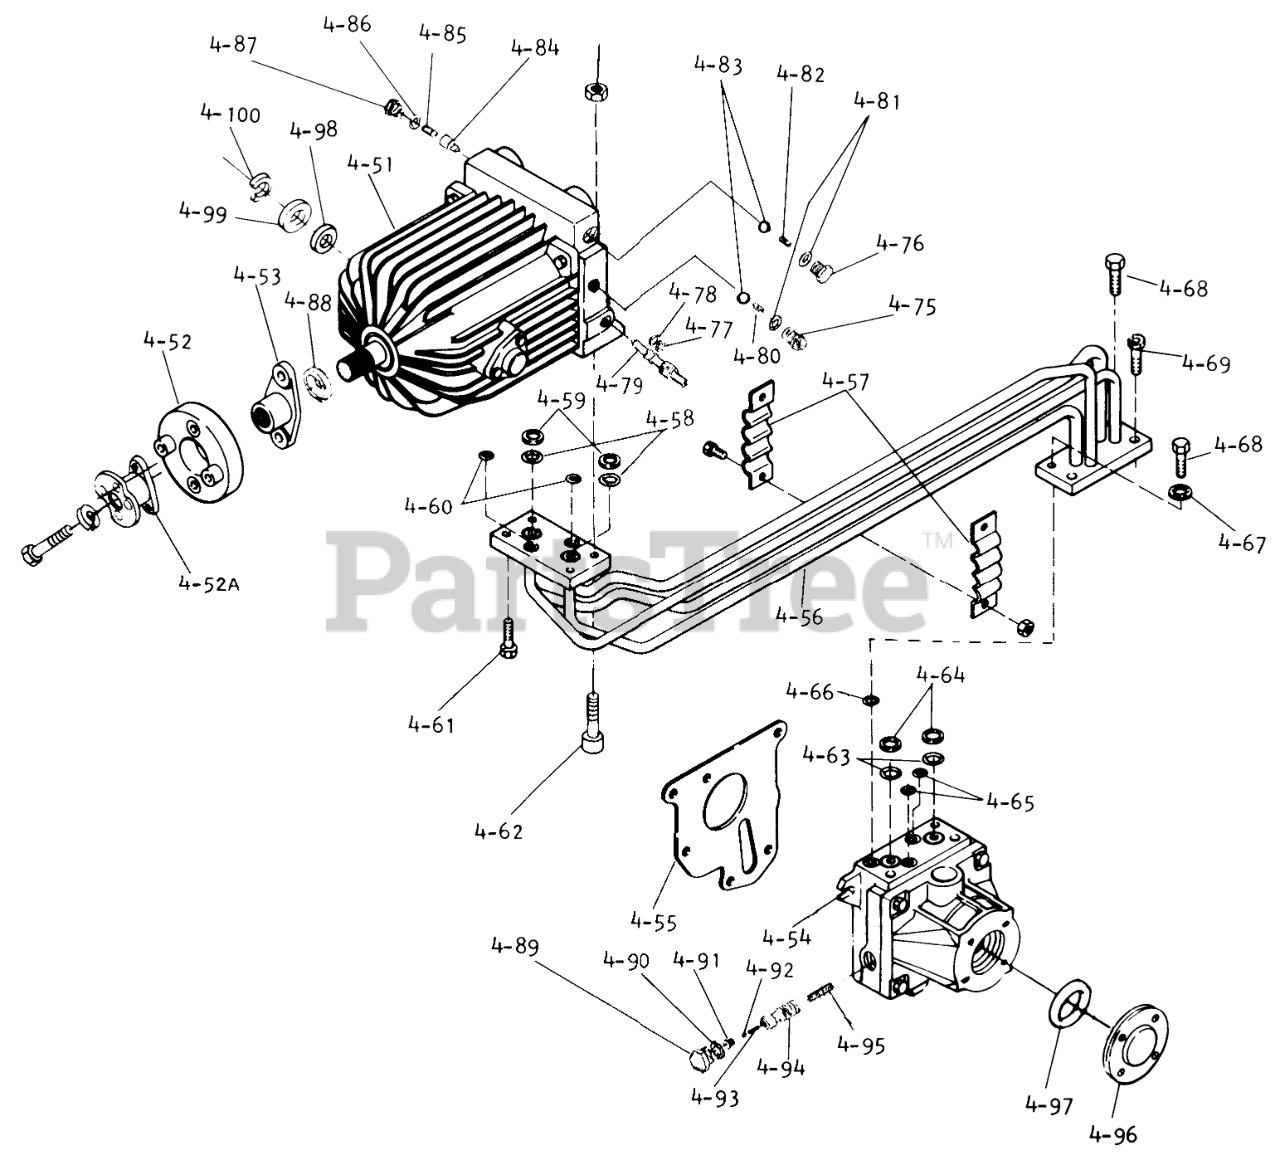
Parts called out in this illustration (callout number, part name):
4-51	Spring
4-52	Coupling
4-52A	Coupling, D-160 Only
4-53	COUPLING DRIVEN R
4-54	Hydro Motor Only
4-55	GASKET
4-56	Manifold, Hydraulic
4-57	Clamp
4-58	O RING
4-59	RING BACKUP
4-60	O RING
4-61	Bolt 3/8-16 x 1
4-62	Screw
4-63	O RING
4-64	RING BACKUP
4-65	O RING
4-66	O RING
4-67	SEAL-MANIFOLD BOLT
4-68	Bolt Hex 1/2-13 x 1 1/4
4-69	Bolt 3/8-16 X 1
4-75	PLUG
4-76	Plug
4-77	Back Up Ring
4-78	O-RING
4-79	VALVE
4-80	Spring
4-81	O RING
4-82	Spring Chg. Rel. Valve
4-84	Cone
4-85	Spring-Implement Valve
4-86	O RING
4-88	SEAL
4-90	O-RING
4-91	Valve
4-93	SPRING
4-94	Sleeve
4-95	Spring
4-96	Plate
4-97	O-RING
4-98	SEAL
4-99	WASHER-LAMBERT
4-100	RING-LAMBERT
